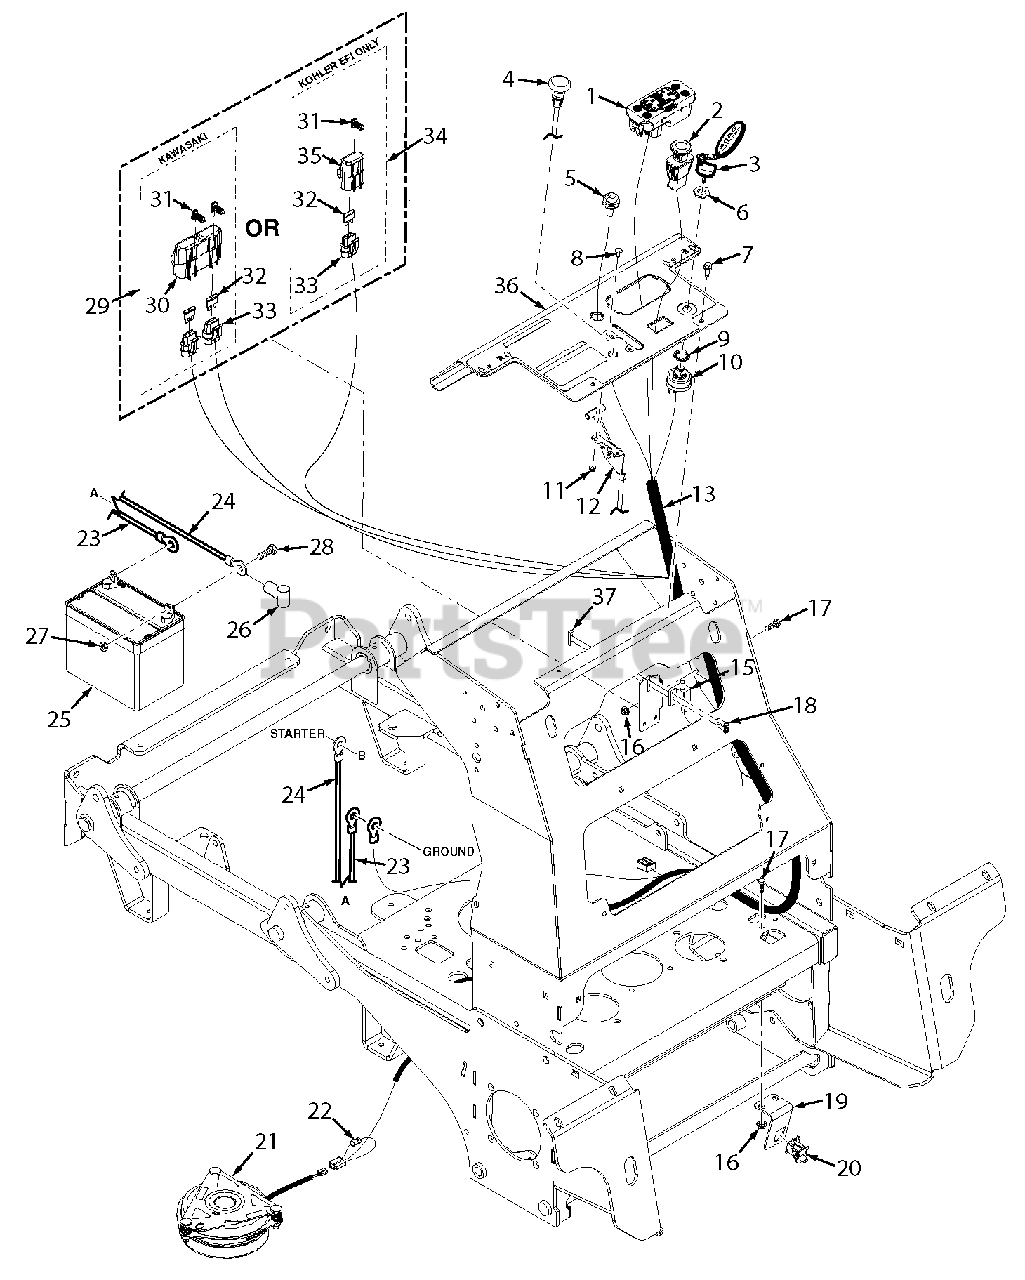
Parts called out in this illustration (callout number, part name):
1	Tiger Eye, Cluster Gauge
2	Switch, PTO
3	Key Assy., w/Fob
4	Choke Control (excludes EFI models)
5	Indicator Light (EFI models only)
6	Nut, Special 5/8-32
7	Screw, 1/4-20 x 3/4" Taptite
8	Bolt, Carriage #10-24 x 1/2"
9	Lockwasher, 5/8" Internal Tooth
10	Switch, Key
11	Nut, Elastic Stop #10-24
12	Throttle Control
13	Wire Harness, SVRII
13	Wire Harness, SVRII-EFI
14	Bracket, Neutral Switch
15	Switch, N/O
16	Nut, Serrated Flange 1/4-20
17	Bolt, Hex Head 1/4-20 x 3/4"
18	Screw, #10-32 x 3/4" Taptite
19	Switch Bracket, Operator Presence
20	Switch
21	Clutch w/Tag GT2.5-FE02 (48 / 52)
21	Clutch w/Tag GT3.5--FE05 (61)
22	Diode, 600V - 6A
23	Battery Cable, 39" Black
24	Battery Cable, 44" Red w/Braid
25	Battery, 350 CCA (not available through Scag)
26	Rubber Boot
27	Nut, 1/4-20
28	Bolt, Hex Head 1/4-20 x 3/4"
29	Double Fuse Assy,\\\.
30	Cover, Sealed Double
31	Clip, Wire
32	Fuse, 20 Amp
33	Fuse Holder
34	Single Fuse Assy.
35	Cover, Sealed Single
36	Control Panel w/Decal
37	Plate, Threaded
